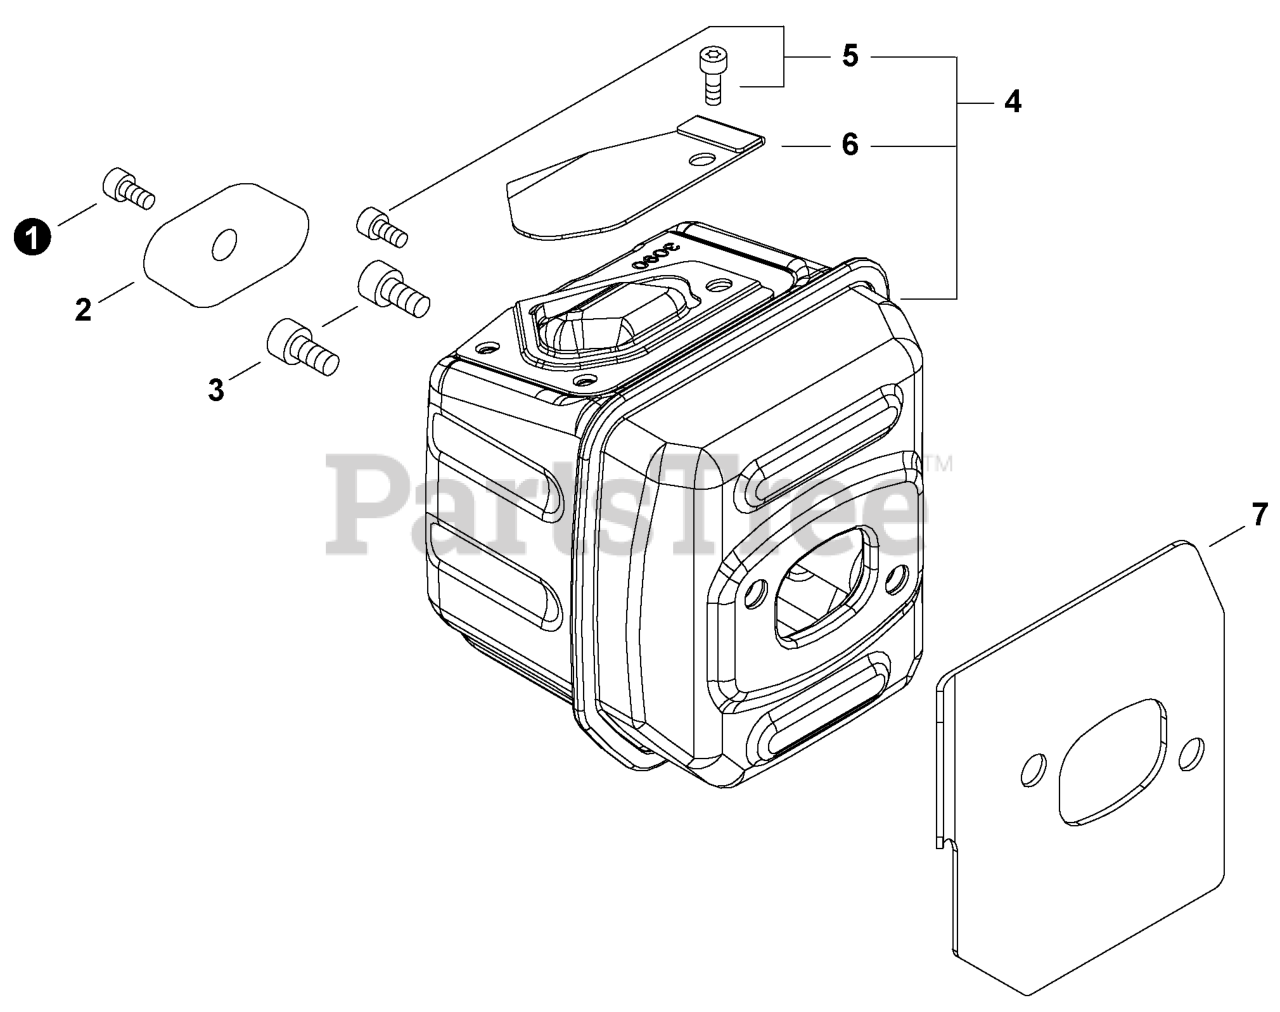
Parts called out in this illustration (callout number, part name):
1	BOLT, TORX 4x8
3	BOLT, TORX 5x16
4	MUFFLER ASSY
5	BOLT, TORX 4x8
6	SCREEN, SPARK ARRESTER
7	GASKET, EXHAUST
